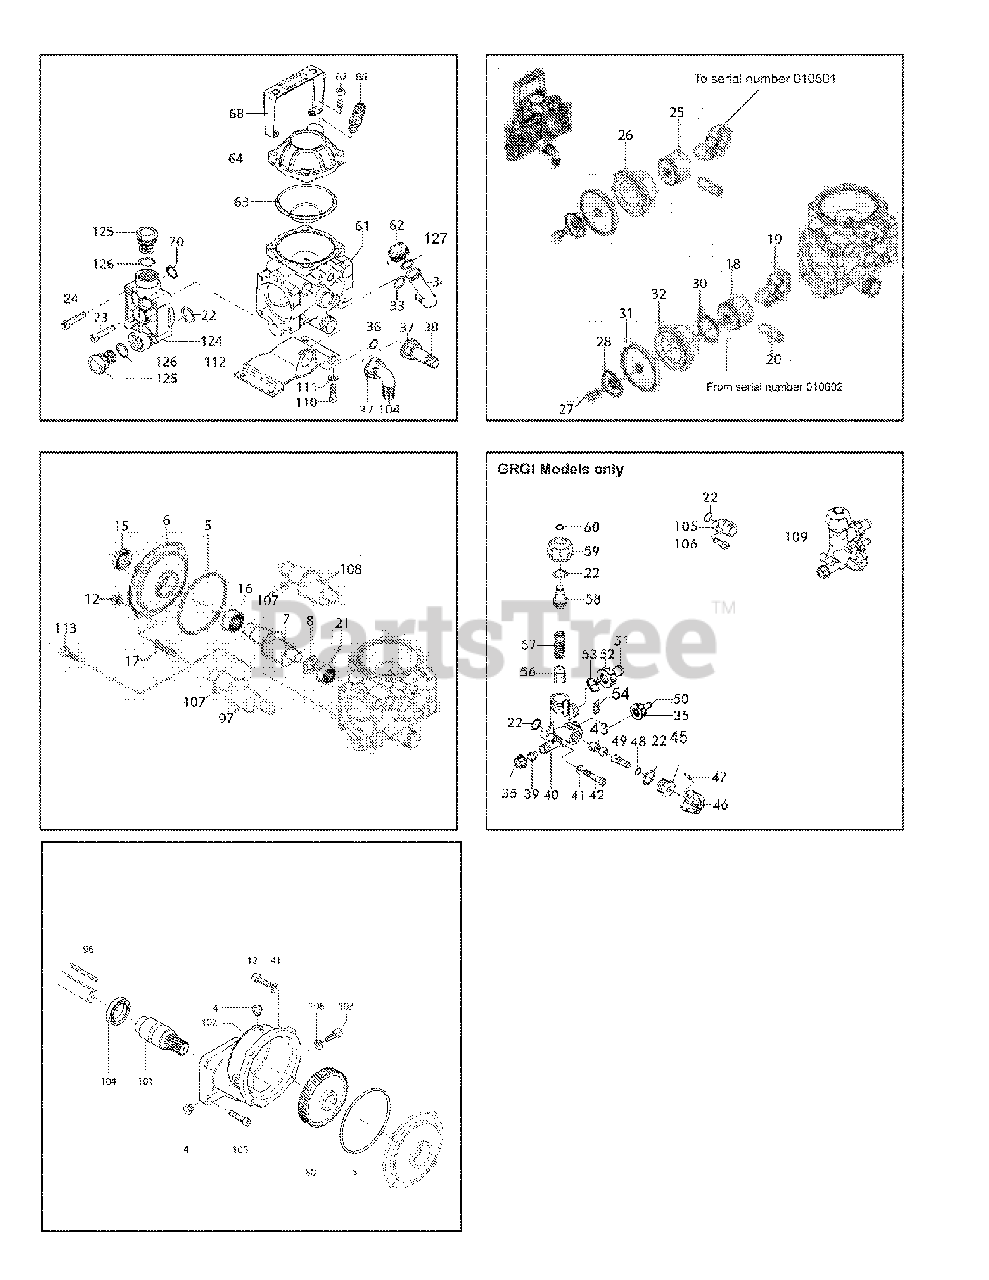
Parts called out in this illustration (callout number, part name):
7	3/4 Solid Shaft
16	Roller Bearing
19	Connecting Rod
21	Roller Bushing
27	Retaining Bolt
31	Diaphragm Desmopan (Std.)
31	Diaphragm Teflon (Opt.)
31	Diaphragm Buna (Opt.)
34	Oil Sight Glass
38	Hose Barb (Inlet) 3/4"
49	Positioning Rod
50	Hose Barb (Outlet) 3/8"
51	Hose Barb (Bypass) 5/8"
54	ATM Scale Adhesive
56	Lower Spring Guide
58	Upper Spring Guide
59	Adjustment Knob
60	Retaining Ring
63	Accumulator Diaphragm (Buna-N)
63	Accumulator Diaphragm (Teflon)
64	Upper Air Chamber
101	Driver Gear, 3/4" shaft only
101	Driver Gear, 5/8" shaft only
103	Locating Bolt
105	Flange, 1/2" NPT
108	Shaft "GR-Version", 3/4"
125	Valve Assembly
